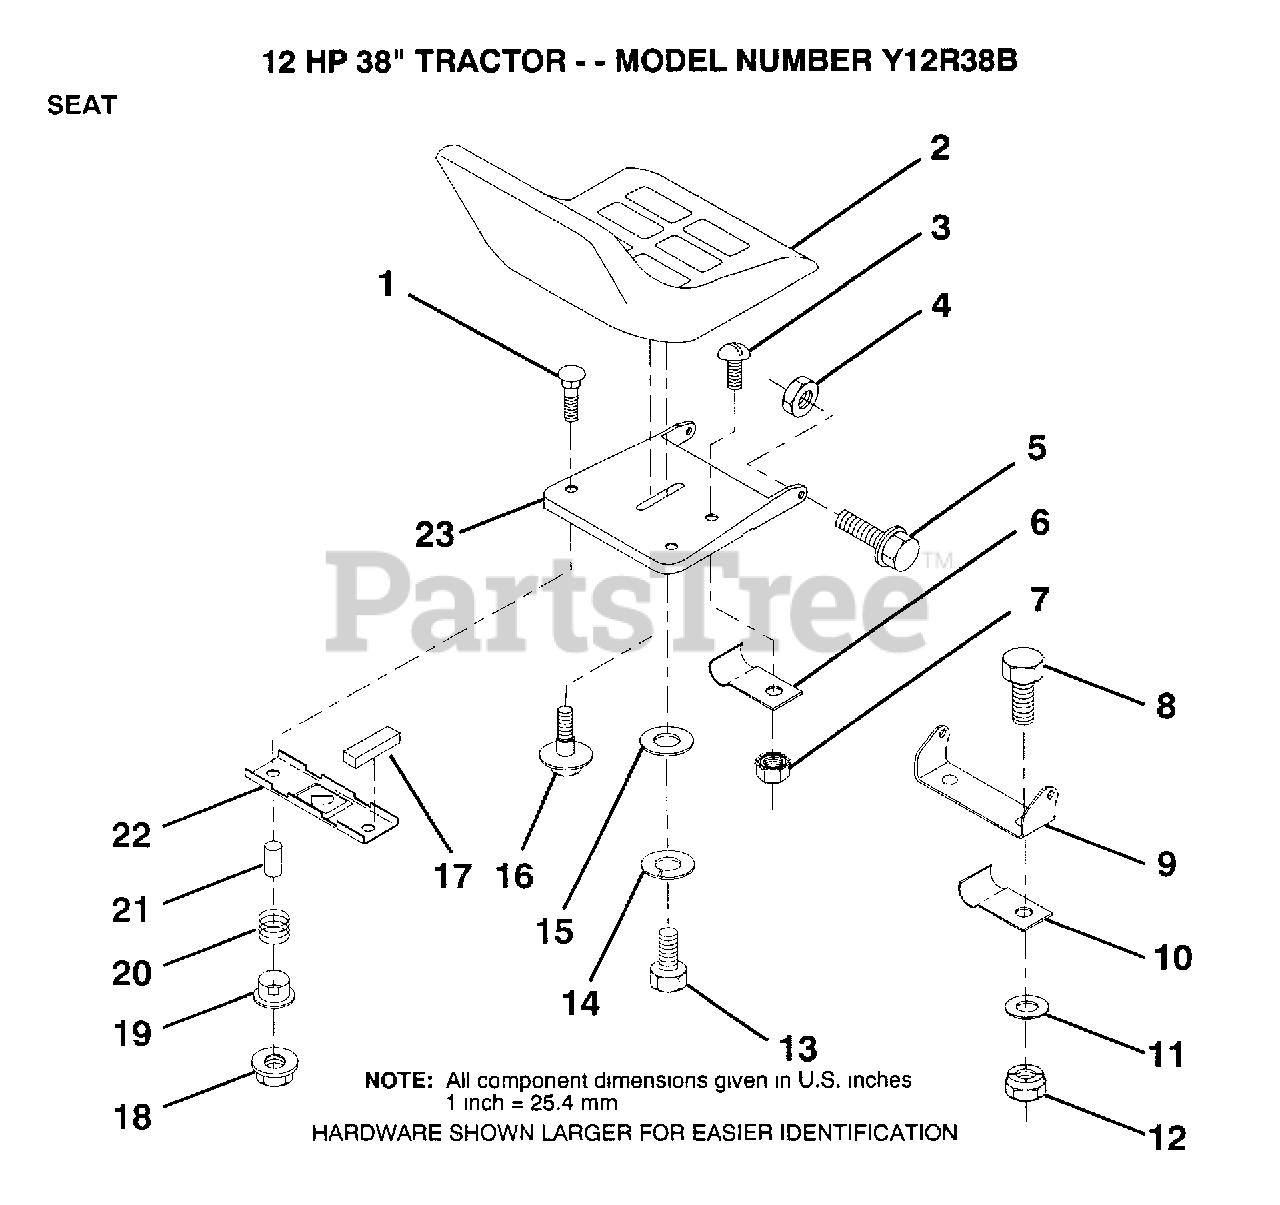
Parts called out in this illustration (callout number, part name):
7	"NUT,KEPS"
10	"CLIP,INSULATOR"
11	WASHER
13	BOLT
14	LOCKWASHER
15	WASHER
16	"BOLT,SHOULDER"
17	STRIP FORM
19	BUSHING
20	SPRING
21	SPLIT SPACER
22	BRKT SWITCH
